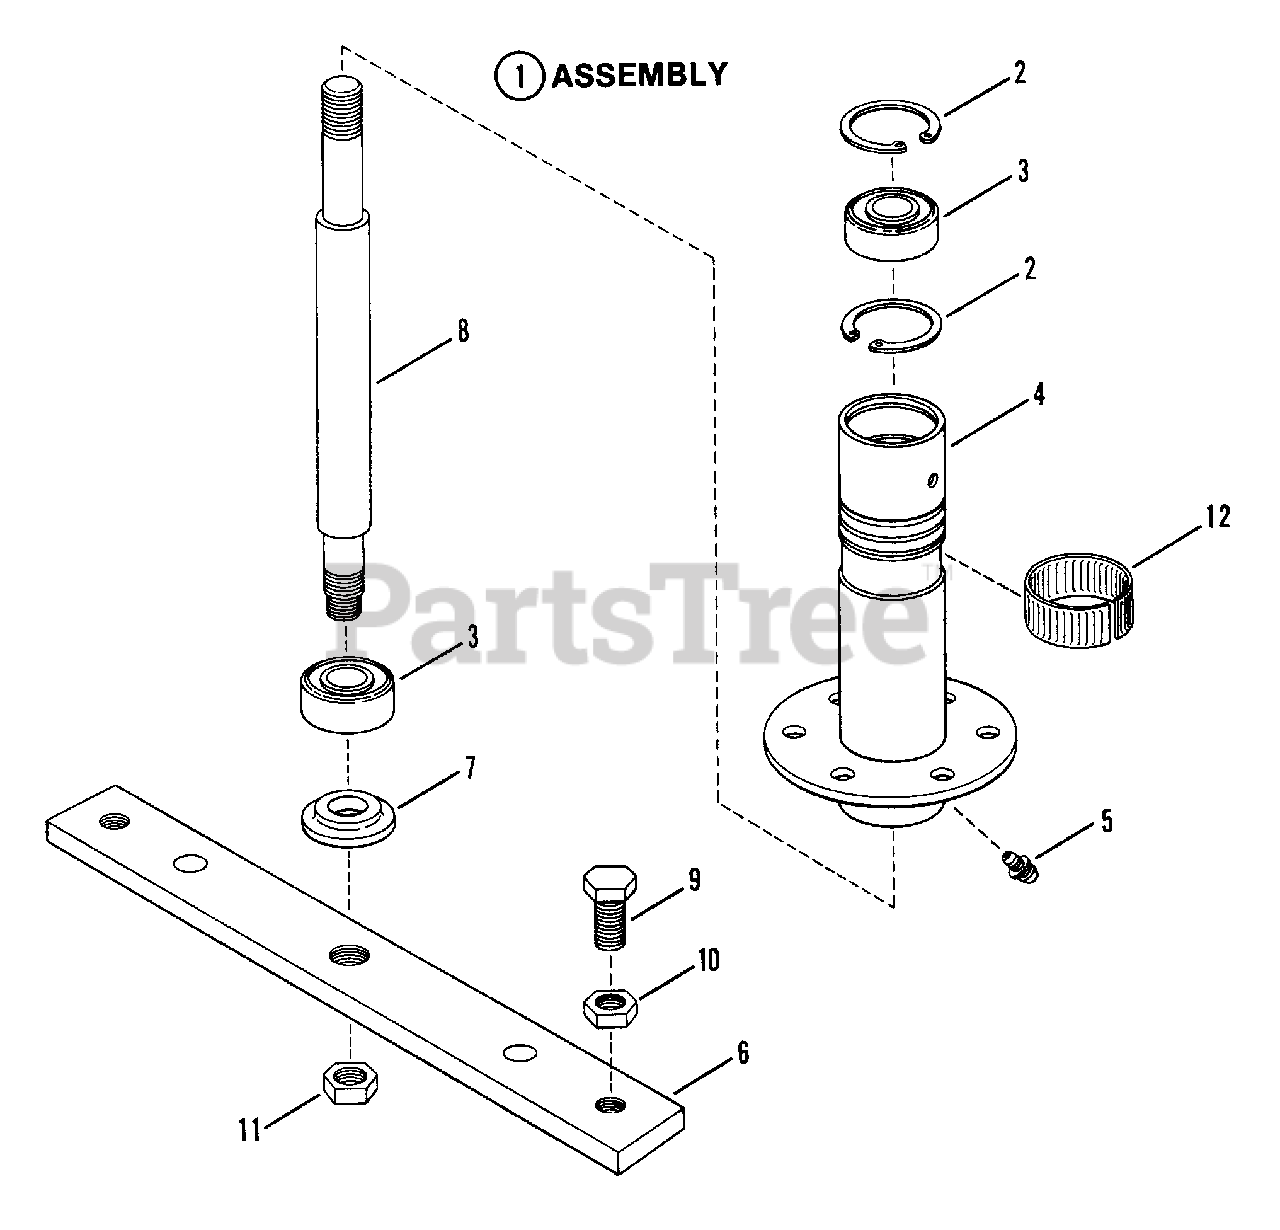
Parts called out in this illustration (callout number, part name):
1	ASSEMBLY, Spindel Housing
2	RING, Retaining
3	BEARING, Spindle
4	HOUSING, Spindle
5	FITTING, Lube (Press fit for .187 hole-no ball)
6	HOLDER, Blade
7	WASHER, Spindle
8	SPINDLE, Shaft (10.237" Long)
9	SCREW, 1/2-20 x 1" Hex Head Cap
10	JAM-NUT, 1/2-20 Hex
11	NUT, 5/8-18 Hex Lock
12	RING, Tolerance
